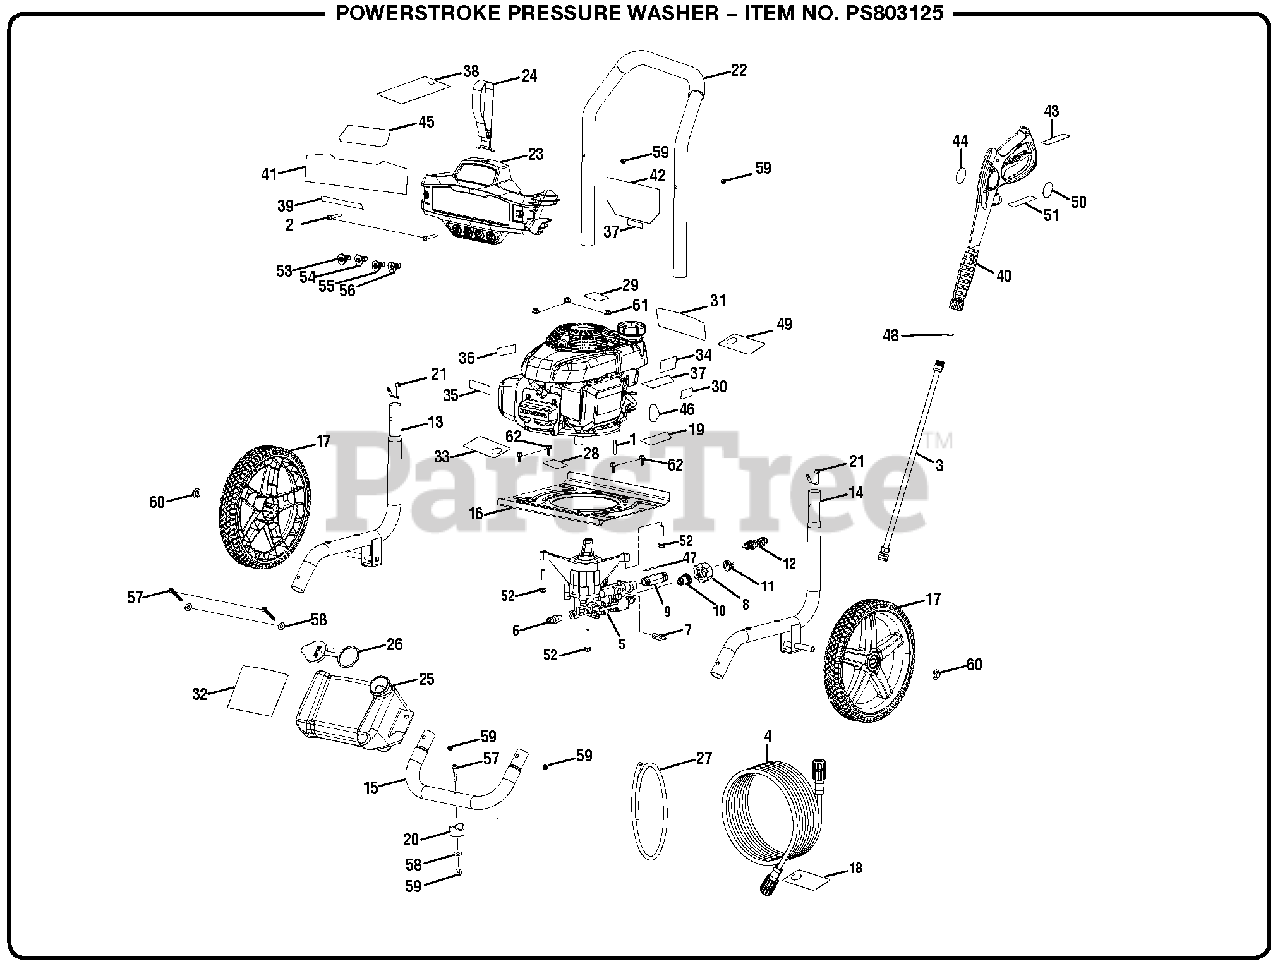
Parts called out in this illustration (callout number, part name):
1	Output Shaft Key
2	Bolt (M6 x 42 mm, T30 Torx Pan Hd.)
3	Spray Wand
5	Pump
6	Thermal Release Valve
7	Soap Injector Kit
8	Inlet Filter Adapter Insert
9	Outlet Tube
10	Inlet Filter Connector
11	Inlet Filter Screen
12	Unloader Valve Assembly
13	Left Frame Assembly
14	Right Frame Assembly
15	Front Frame Assembly
16	Engine Plate
18	High Pressure Hose Hangtag
19	EMC ICES-2/NMB-2 Label
21	Handle Spring Clip
22	Handle Assembly
23	Hose and Nozzle Holder Assembly
24	Hose Holder Strap
25	Soap Tank
26	Soap Tank Cap
27	Chemical Siphon Tube
28	Add Oil Label
29	Combustion Warning Label (English/Spanish)
30	Choke Label
31	Danger Label (English/Spanish)
32	Soap Tank Label
33	Oil Dipstick Hangtag
34	E85 Label
35	Logo Label
36	Hot Surface and Exhaust Label
37	Inquiries Label
38	Nozzle Hangtag
39	Nozzle Callout Label
40	Trigger Handle Assembly
41	Performance Label
42	Quick Start Label
43	Trigger Handle Warning Label (French/Spanish)
44	Powerstroke Spray Wand Logo Label
45	Logo Label
46	Engine Label
47	High Pressure Hose Outlet Label
48	O-Ring (9.5 x 2.65, NBR Shore A 90)
49	Danger Hangtag
50	Trigger Handle Warning Label (English)
51	Trigger Handle Specifications Label
52	Bolt (M8 x 60mm, Hex Hd.)
53	0deg Nozzle
54	25deg Nozzle
55	40deg Nozzle
56	Soap Nozzle
57	Screw (M6 x 48 mm, T-30 Torx Hd.)
58	Washer (1/4 in.)
59	Lock Nut (M6)
61	Lock Nut (M8)
62	Flange Bolt (M6 x 16mm, Hex Hd.)
